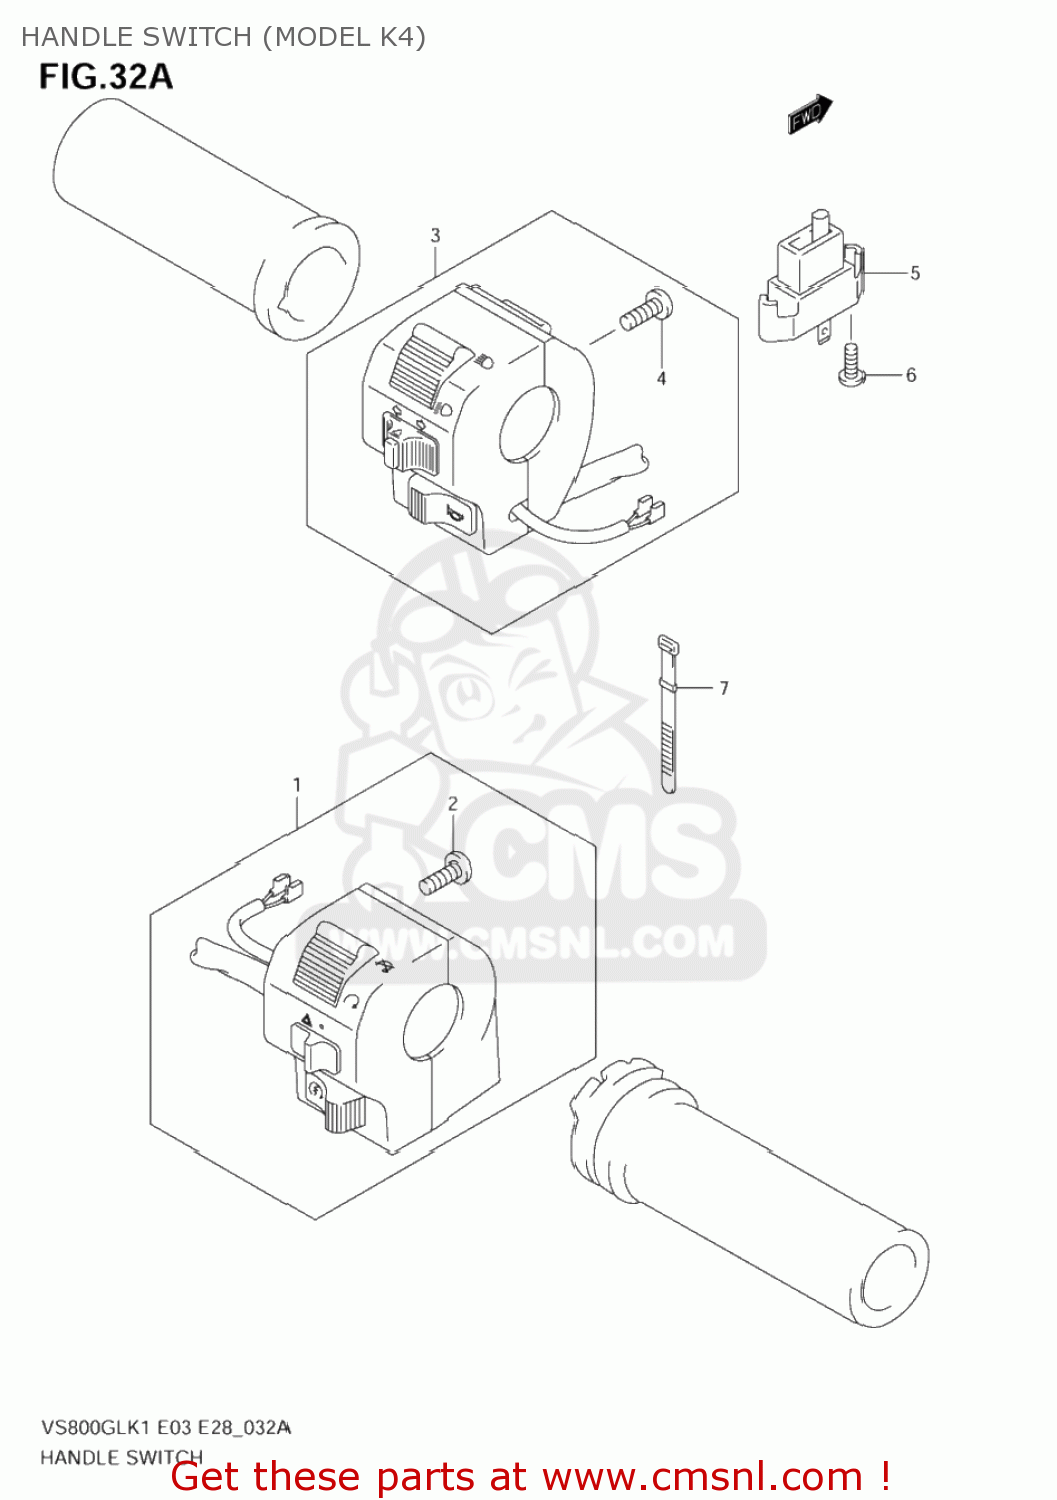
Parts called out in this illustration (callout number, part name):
1	SWITCH ASSY,HANDLE,R
2	SCREW
3	SWITCH ASSY,HANDLE,L
4	SCREW
5	SWITCH ASSY,CLUTCH
6	SCREW
7	CLAMP
